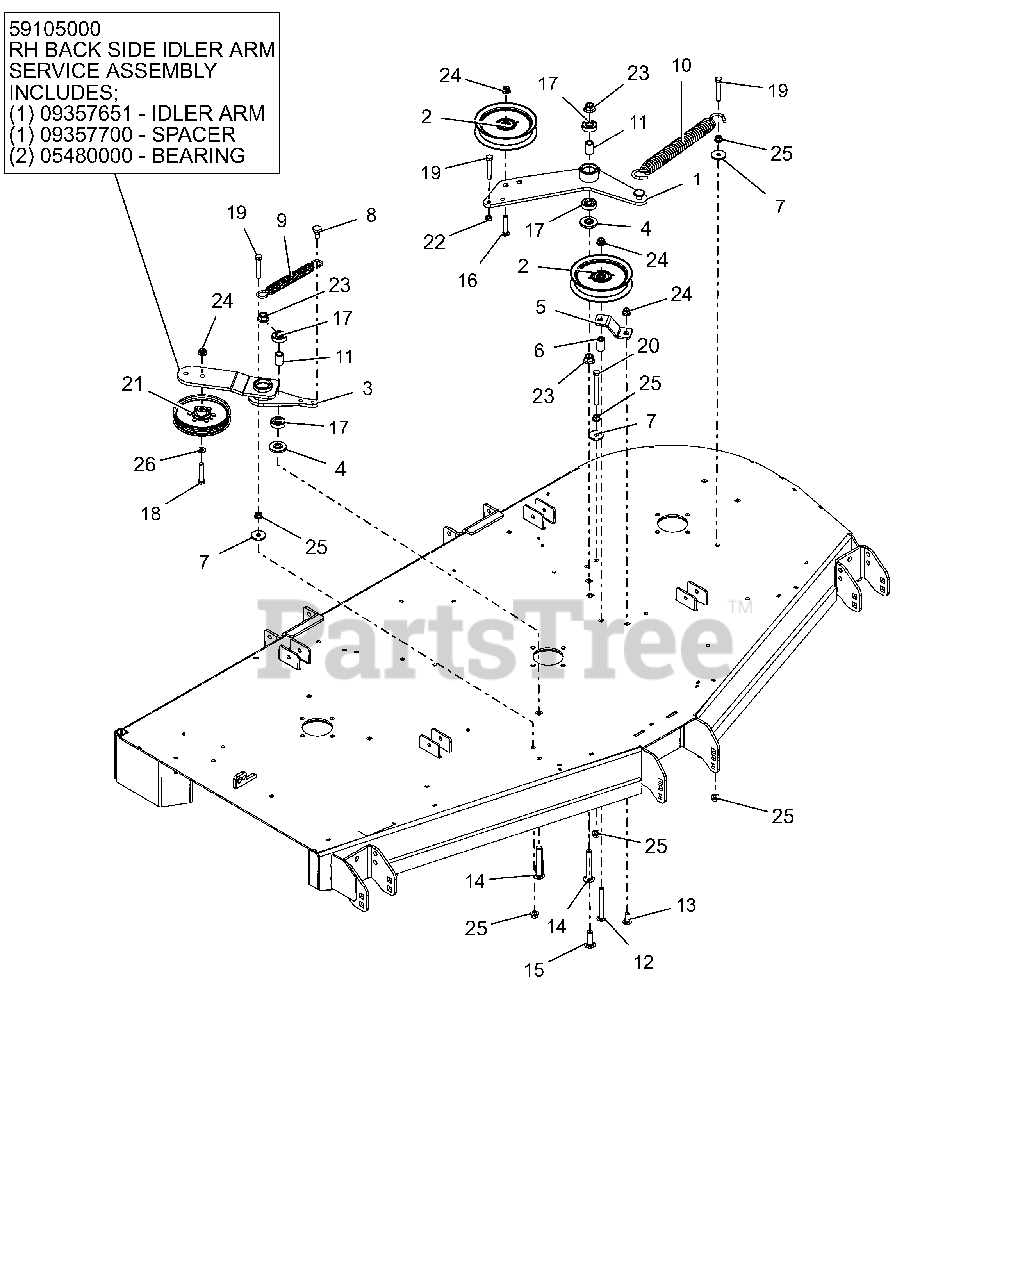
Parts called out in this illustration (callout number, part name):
1	DECK PTO IDLER ARM WLDMT - BLK
2	IDLER, FLAT 5.00"
3	DECK RH IDLER ARM WMT - BLK
3	RH BACKSIDE IDLER ARM ASSEMBLY
3	SPACER .510 X .75 X 1.1485
3	BRG-BALL .50X1.38X.438 SEALED
4	SPACER, IDLER ARM
5	PTO FIXED IDLER MTG BRKT -RED
6	BUSHING, SLV .380X.750X1.190
7	WSHR-FL-STL .406X1.375X.135 YZ
8	BLT,SHLDR EP .38-16X.30 HEX YZ
9	SPRING, EXTENSION
10	SPRING, EXTENSION
11	SPACER .510 X .75 X 1.1485
12	@BLT-RHDSSQNK .38-16X3.50 G5YZ
13	@BLT-RDHDSHSQNK.38-16X1.0 G5YZ
14	BLT,RDHDSQSHNK.50-13X3.25 G5YZ
15	BLT-RDHDSHSQNKFT.50-13X1.50 G5
16	BLT-RDHDSQNK .38-16X2.00 SHTYW
17	BRG-BALL .500X1.38X.437
18	@BLT-HEX .38-16X2.00 GR5 YWZC
19	@BLT-HEX .38-16X2.25 GR5 YWZC
20	@BLT-HEX .38-16X3.50 GR5 YWZC
21	PULLEY, FLAT IDLER
22	NUT-HEX-JAM .375-16 YWZC
23	@NUT-LK-NYL-FLG .50-13 YWZC
24	@NUT-LK-NYL-FLG .38-16 YWZC
25	@NUT-SPNLK-FLG .375-16 YWZC
26	@WSHR-FL-STL.406X.812X.065 YWZ
